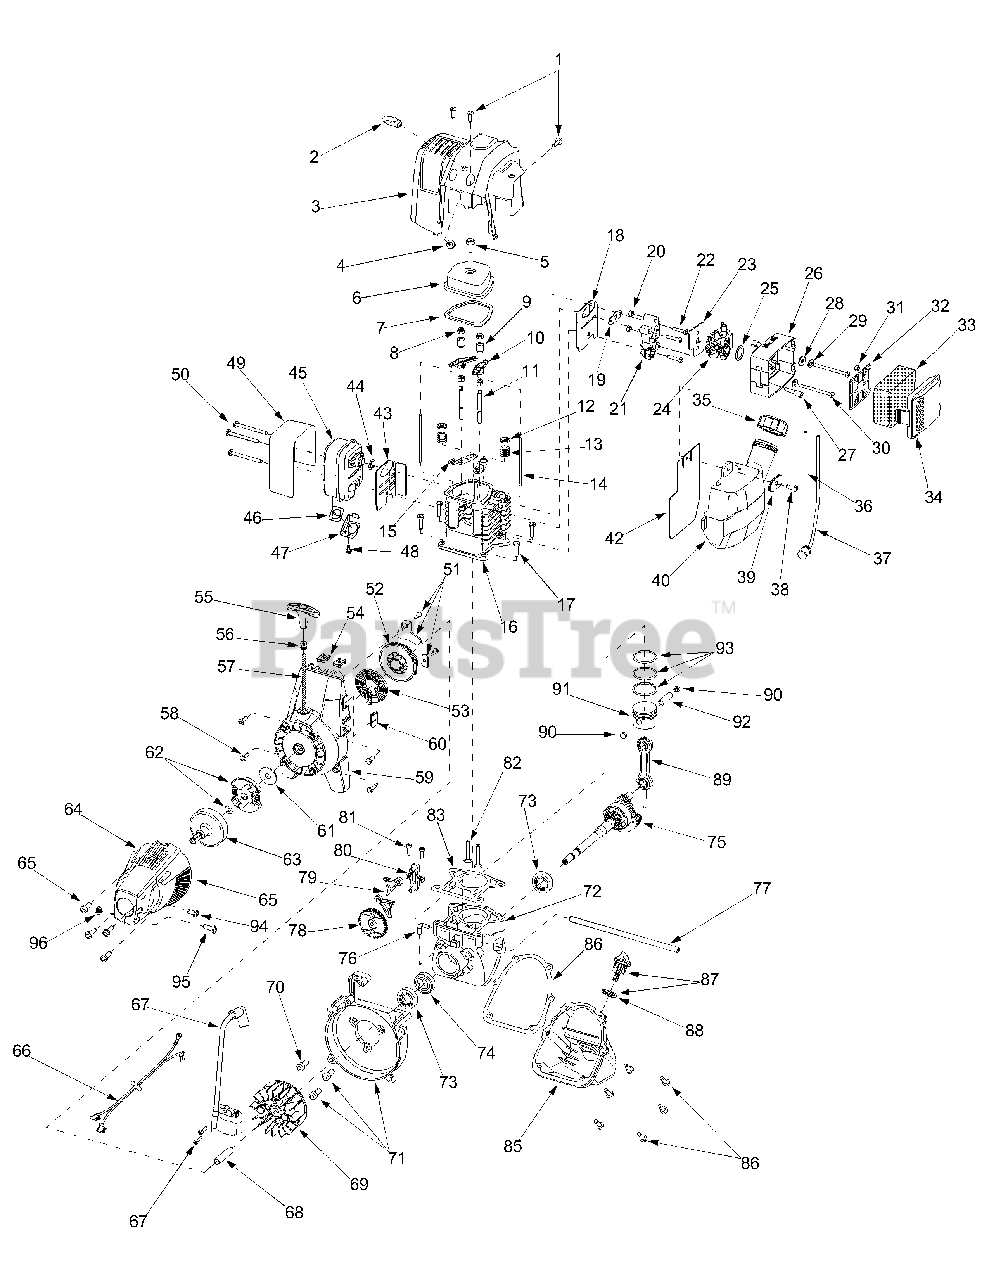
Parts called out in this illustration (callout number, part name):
1	Engine Cover Screws
2	Starter Rope Eyelet
3	Engine Cover
4	Eyelet Nut
5	Valve Cover Screw
6	Valve Cover
7	Valve Cover Gasket
8	Rocker Adjustment Nut
9	Rocker Arm Pivot
10	Rocker Arm
11	Rocker Arm Stud
12	Valve Spring Retainer
13	Valve Spring
14	Push Rod
15	Push Rod Guide
16	Cylinder Head (incl. 11& 15)
17	Cylinder Screw
18	Intake Baffle
19	Carburetor Mount Gasket
20	Nut
21	Carburetor Mount (incl 20)
22	Carburetor Mount Screw
23	Carburetor Gasket
24	Carburetor w/ Primer
25	Air Filter Gasket
26	Filter Cover Assy (incl. 27,28,31-34)
27	Breather Tube Assembly
28	Grommet Washer
30	Carburetor Stud
31	Keps Nut
32	Air Filter Plate
33	Air Filter
34	Air Filter Cover
35	Fuel Cap
36	Fuel Return Line
37	Fuel Pick-up Line w/ Filter
40	Fuel Tank Assy (Incl. 35-37)
41	Fuel Tank Bushing
42	Fuel Tank Shield
43	Muffler Baffle
44	Muffler Gasket
45	Muffler
46	Spark Arrestor Screen
47	Screen Cover
49	Muffler Shield
50	Muffler Mounting Screw
51	Palnut
52	Recoil Pulley
53	Recoil Spring
54	Nut Clip
55	Pull Handle
56	Rope Guide
58	Starter Housing Screw
59	Starter Housing Assy (incl. 51-58)
60	Wire Grommet
61	Clutch Washer
62	Clutch w/ Washer
63	Clutch Drum
64	Clutch Cover
65	Clutch Cover Screw
66	Switch Assembly
67	Ignition Module w/ Screws
69	Flywheel
71	Shroud Assembly w/ Screws
72	Crankcase Assembly
73	Oil Seal
74	Bearing
75	Crank Shaft
76	90° Elbow
77	Breather Hose
78	Cam Gear
79	Cam Follower Set
80	Cam Bracket
81	Cam Bracket Screw
82	Intake & Exhaust Valves
83	Cylinder Gasket
84	Oil Pan Gasket
85	Oil Pan (Includes 84 & 86)
86	Oil Pan Screw
87	Dipstick Assembly
89	Connecting Rod
90	Wrist Pin Button
91	Piston
92	Wrist Pin
93	Piston Ring Set
94	Antirotation Screw
95	Screw
